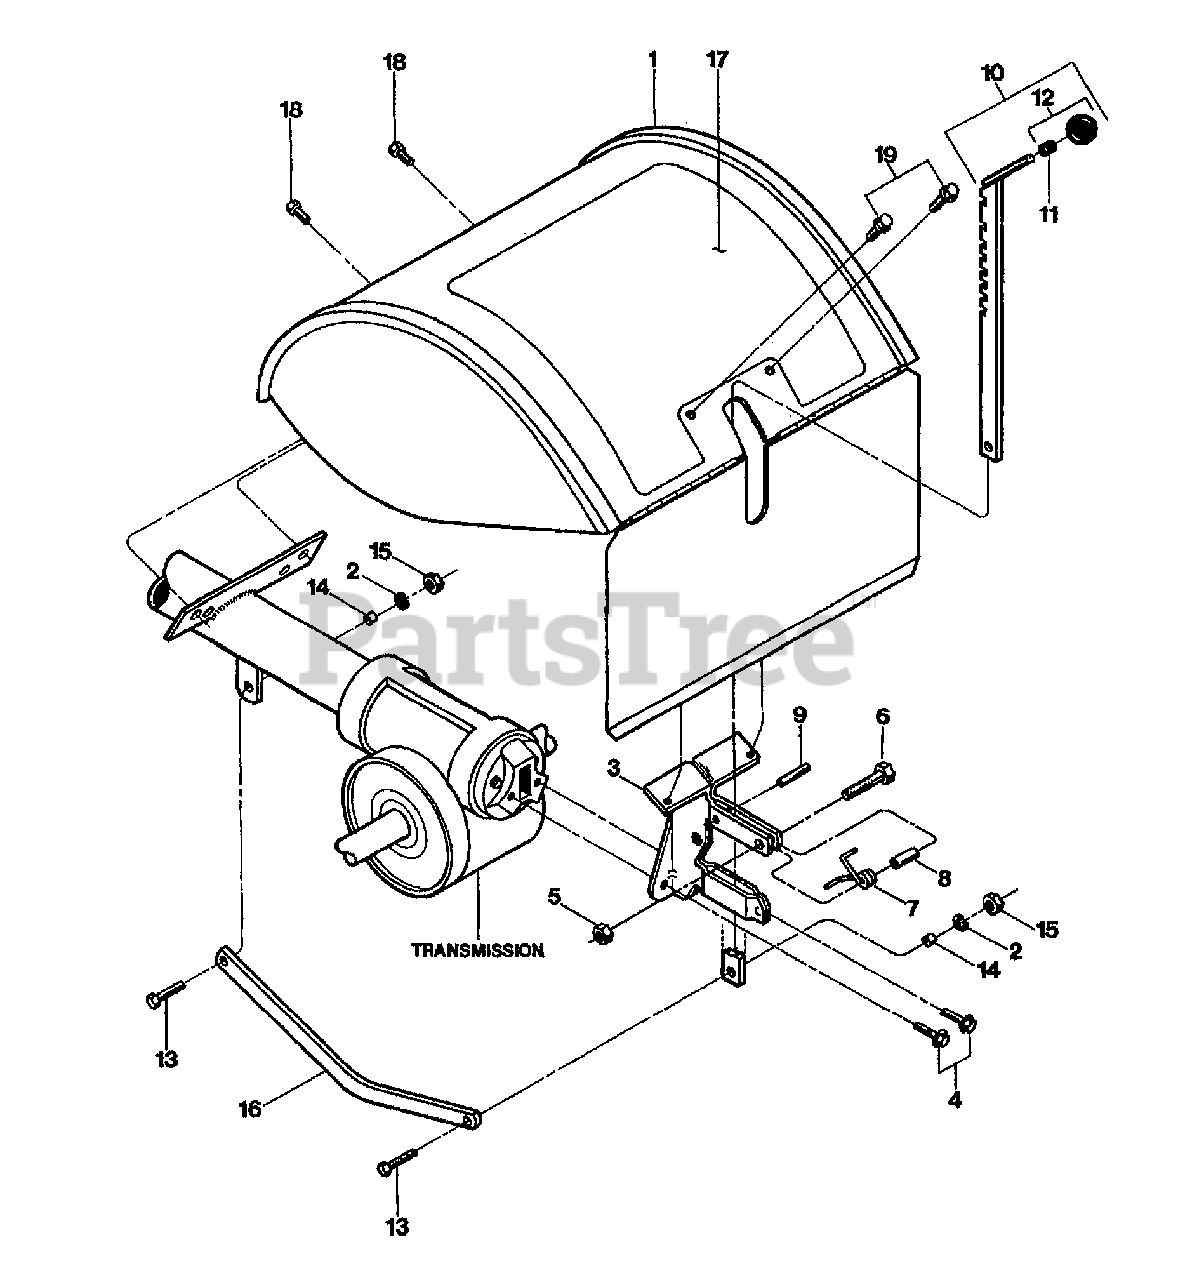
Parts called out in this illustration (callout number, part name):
1	HOOD W/DECAL ECONO OPC (INCL. 17)
2	WASHER-LK .375 @ DEPL
3	BRKT W/ROLL PIN (9308) (INCL. 9)
4	SCR-HFLK 5/16-18X.75 ZP
5	NUT-LK 1/4-20
6	SCR-HH 1/4-20X1.0
7	SPRING-TORSION
8	SPACER-.250X.343X.375
9	PIN-ROLL .25 X 1 (SPIRAL)
10	DEPTH REGULATOR W/KNOB (INCL. 11 & 12)
11	RING-TOLERANCE .5325 ID
12	KNOB-CONTROL (INCL. 11)
13	SCR-HH 3/8-16X1.25
14	BUSHING-.5X.375X.3
15	NUT-HEX 3/8-16 ZP
16	DRAG BAR-BENT
17	DECAL-HOOD OPER INST
18	SCR-HWH 5/16-18 X .5 STH
19	SCR-HWH 1/4-20 X .5 STH
